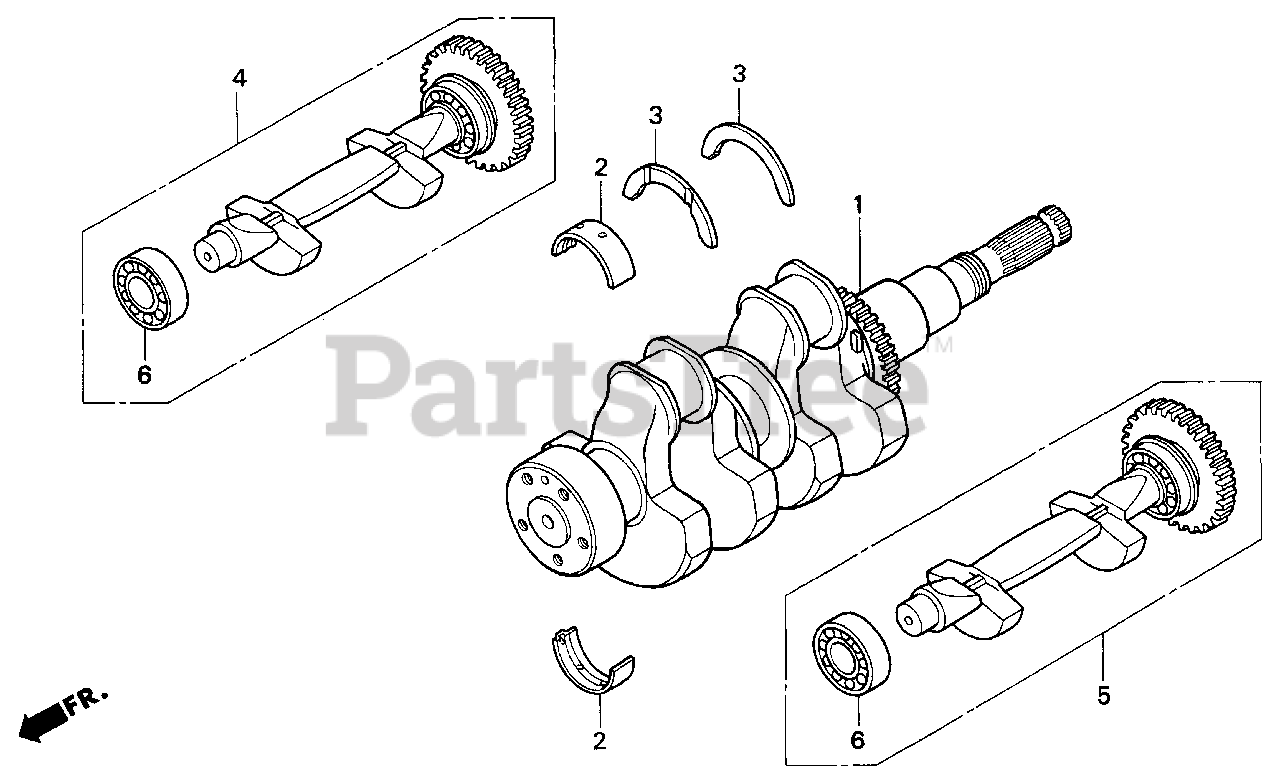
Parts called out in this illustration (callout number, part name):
1	CRANKSHAFT
2	BEARING A, MAIN (BLUE)
2	BEARING B, MAIN (BLACK)
2	BEARING C, MAIN (BROWN)
2	BEARING D, MAIN (GREEN)
2	BEARING E, MAIN (YELLOW)
2	BEARING F, MAIN (PINK)
2	BEARING G, MAIN (RED)
3	WASHER, THRUST
4	WEIGHT, R. BALANCER
5	WEIGHT, L. BALANCER
6	BEARING, RADIAL BALL (6203)
